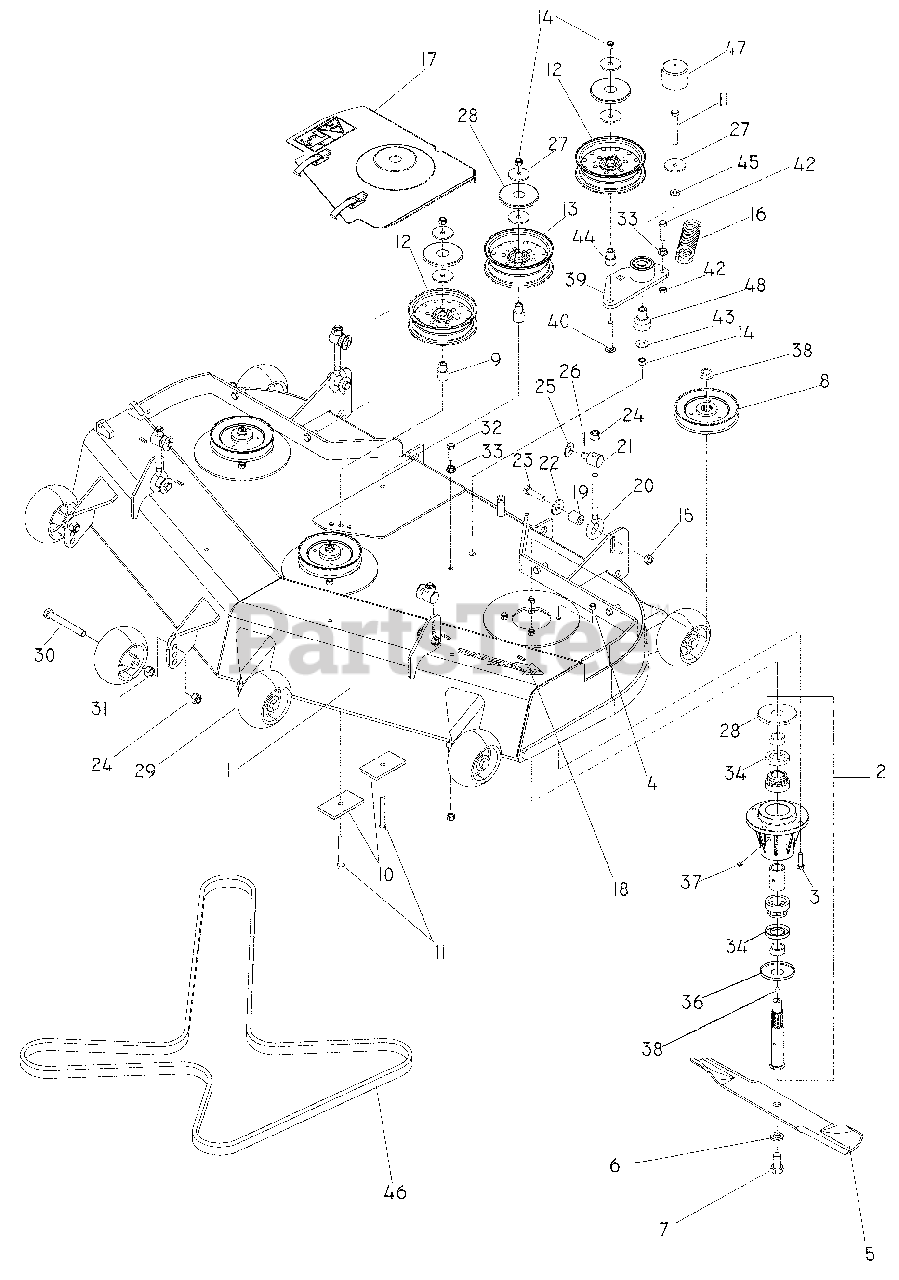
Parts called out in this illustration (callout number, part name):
1	DECK W/DECALS
2	SPINDLE
3	HCS 5/16-18 x 1¼
4	NUT 5/16-18 HEX NYLOC
5	BLADE, 18"
6	WASHER 5/8 SLW
7	HCS 5/8-18 x 1¼
9	IDLER BUSHING
10	PAD, PAINTED
11	HCS 3/8-16 x 3
12	IDLER PULLEY
13	IDLER PULLEY
14	NUT 3/8-16 HEX NYLOC
15	NUT 7/16-14 HEX CTRLK GR A
17	BELT SHIELD ASM RT
18	DECAL, TUNNELRAM
22	SPRING WASHER
23	HCS 7/16-14 x 1¾
24	NUT ½ -13, NYLOC
25	WASHER, ½ STD FLT
26	PIN COTTER 1/8 x 1
27	WASHER - 3/8 SPECIAL
28	TOP DUST CAP
29	WHEEL, GAUGE
30	HHB ½-13 x 4
31	NUT ½-13 HEX
32	HCS 3/8-16 x 1¼
33	NUT 3/8-16 HEX WHIZLK
34	SHAFT SEAL
35	BOTTOM DUST CAP
36	GREASE POPPET
38	NUT FLANGE ¾-16
39	ARM, IDLER - W/BEARINGS
40	RHSNB 3/8-16 x 2¾
41	HCS 3/8-16 x 1½ GR 8
42	NUT 3/8-16 HEX JAM
43	WASHER, 3/8 FLAT STD
44	BUSHING, IDLER
45	WASHER, 3/8 SAE FLT
46	DECK BELT
47	CAP, VINYL
48	PIVOT BEARING
